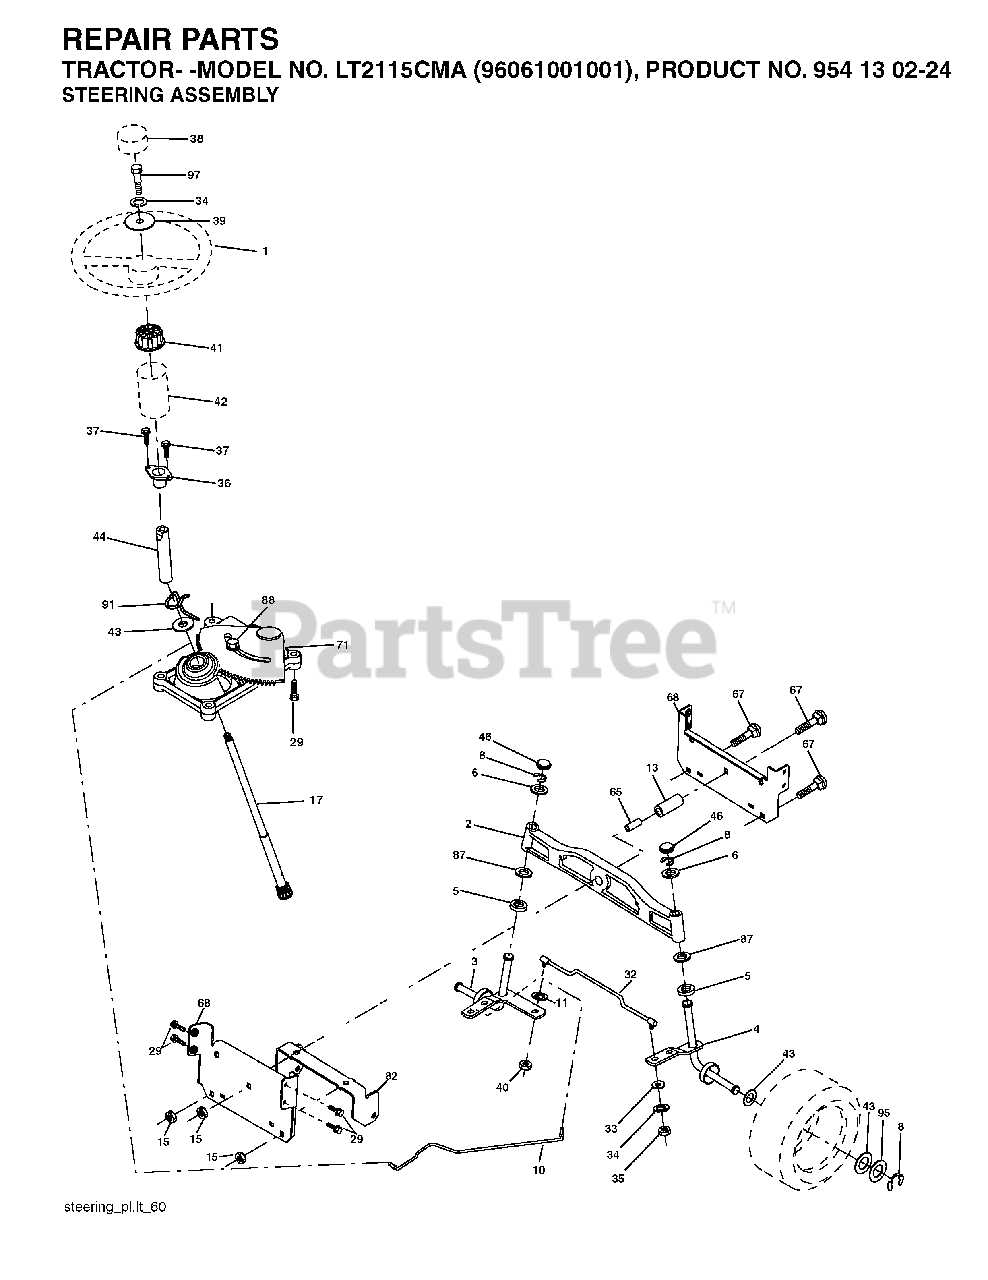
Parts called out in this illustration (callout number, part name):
1	WHEEL.STEERING.PREM.2.BLK
2	AXLE ASSY FRONT
3	SPINDLE.ASM.LH.15"TIRES
4	SPINDLE.ASM.RH.15"TIRES
8	RING CLIP
10	DRAGLINK.15".TIRES.2001
11	WASHER, LOCK 3/8
13	TUBE, PIVOT AXLE
15	NUT
17	SHAFT STEERING SPLINE
29	SCREW, 3/8-16X3/4
32	ROD.ASM.TIE.BALL.JOINT.NOVAN
33	WASHER M
34	LOCKWASHER
35	NUT, CROWNLOCK
36	BUSHING, STEERING
38	INSERT.CAP.STRG.WH.BLACK
39	WASHER.11/32
40	NUT CROWNLOCK 3/8-24
41	ADAPTER, WHEEL STNG..
42	BOOT.STEERING.SHAFT.BLACK
44	SHAFT.EXTEN.STRG.SPLINE
46	CAP.SPINDLE
65	SPACER BRACE AXLE
67	BOLT CARRIAGE
68	BRACE.AXLE.15"TIRES
71	STEERING ASM
82	BRACKET
87	WASHER, FLAT .781 X 1 1/2"
88	BOLT, SHOULDER 7/16-20
91	CLIP.STEERING
95	WASHER.HARDENED
